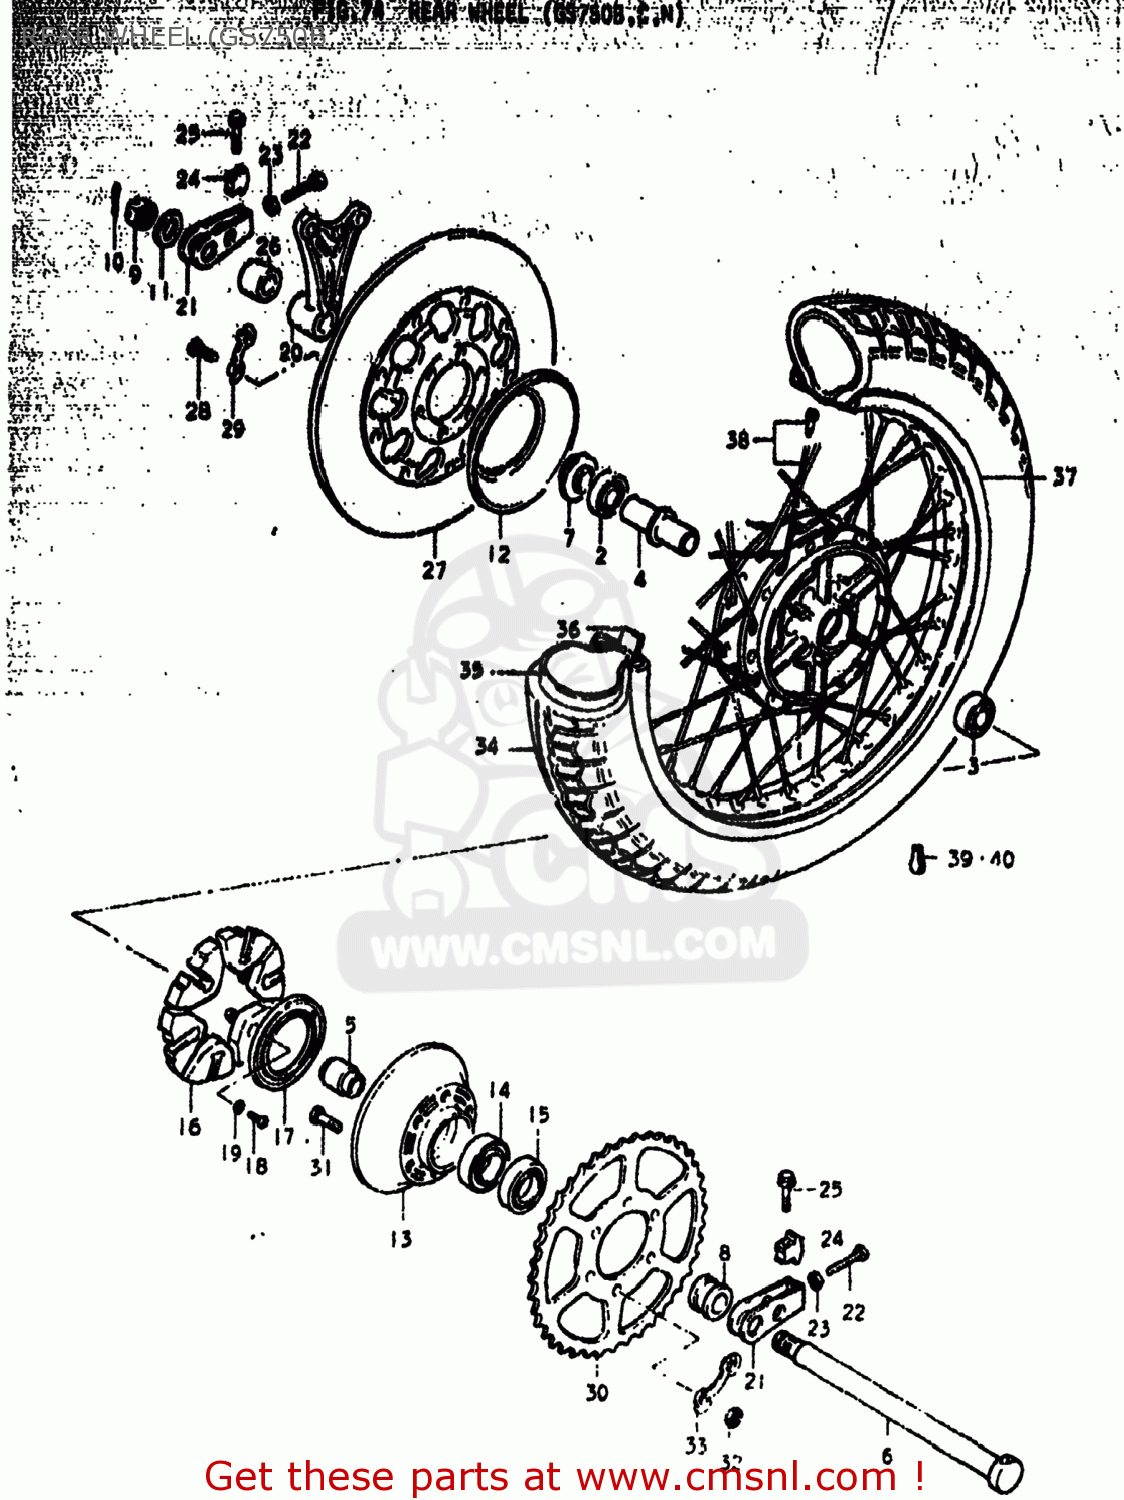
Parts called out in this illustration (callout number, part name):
1	DRUM,REAR HUB
2	BEARING
3	BEARING, LH
4	SPACER,REAR HUB BEARING
5	SPACER,REAR HUB BEARING
6	AXLE,REAR
7	SPACER,REAR AXLE
8	SPACER(20X33X28.3)
9	NUT 18MM
10	PIN,COTTER
11	WASHER(19X34X4)
12	COVER,REAR WHEEL HUB
13	DRUM,REAR SPROCKET MOUNT
14	BEARING
15	SEAL,OIL(33X62X7)
16	ABSORBER,REAR HUB SHOCK
17	PLATE,REAR HUB SHOCK ABSORBER
18	SCREW
19	LOCK WASHER
20	BRACKET,REAR CALIPER
21	ADJUSTER,CHAIN
22	BOLT
23	NUT
24	SUPPORTER,CHAIN ADJUST
25	BOLT,FRONT
26	SPACER(20X38X12)
27	DISC,BRAKE
28	BOLT(8X30)
29	WASHER
30	SPROCKET,REAR
31	BOLT
32	NUT
33	WASHER
34	TIRE
35	TUBE ASSEMBLY,WHEEL,INNER
36	PROTECTOR,WHEEL,INNER
37	RIM,WHEEL
38	SPOKE SET,REAR
39	BALANCER,WHEEL (B)
40	BALANCER,WHEEL (30G)
